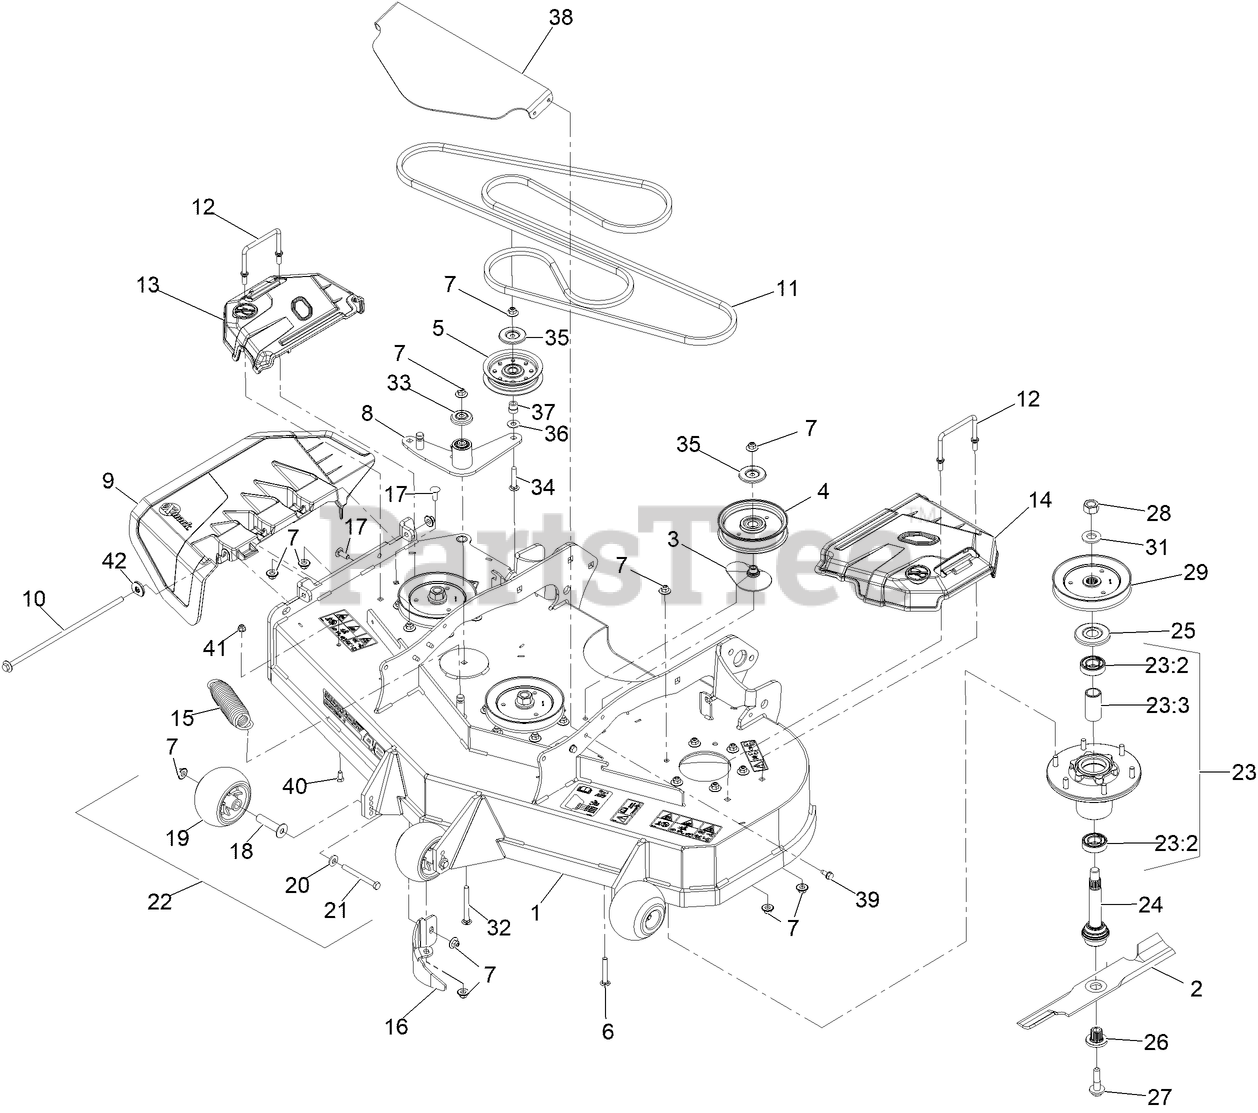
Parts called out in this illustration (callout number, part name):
1	ASM-DECK W/DECALS 484
3	SPACER-PULLEY
4	Pulley-Idler, Flat
6	SCREW-CARR
7	Nut-Nyloc 3/8-16 Flg
8	IDLER ARM ASM W/BEARINGS
9	Chute-Deck Discharge
10	Pin, Chute
11	BELT-B147.4
12	WIREFORM-COVER
13	SHIELD, RT
14	SHIELD, LT
15	SPRING-EXTENSION
16	BAFFLE-DOGLEG,LZS LZX VT48
17	SCREW-CARR
18	AXLE, ROLLER
19	ROLLER-SCALP, ANTI
20	WASHER-BELLEVILLE
21	SCREW-HH 3/8-16 X 3 3/4 GR 8
22	KIT, ANTI-SCALP ROLLER
23	ASM-CUTTER HSG WITH BEARINGS
23:2	BEARING-BALL
23:3	SPACER-BEARING
24	ASM-SPINDLE AND SEAL
25	GUARD-BEARING, TOP
26	BUSHING,SPLINED
27	SCREW,SEMS 1/2-20 X 2.19
28	NUT-HEX
29	Sheave,Blade Drive 5.90
32	SCREW-CARR
33	GUARD-TOP
34	SCREW-CARR
35	SHIELD-DUST
36	WASHER-FLAT
37	BUSHING,IDLER
38	Guard-Front Deck
39	SCREW-THD ROLL, HWH
40	SCREW-HH
41	NUT-HF, NI
42	Retainer, Chute
